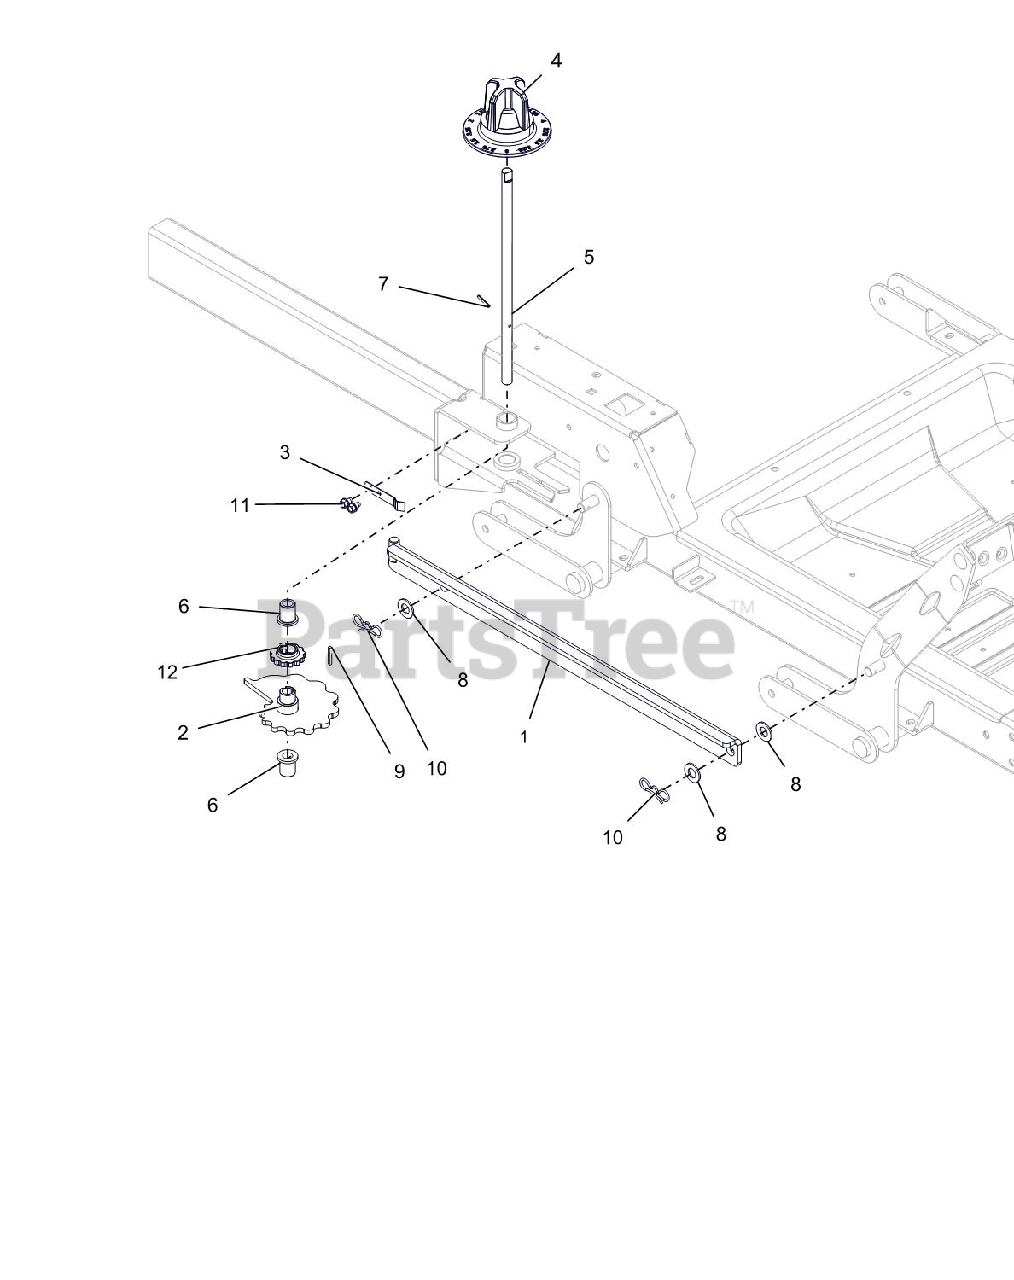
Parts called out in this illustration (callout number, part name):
1	WLDMT, HOC LINK
2	WLDMT, HOC CAM
3	ARM, HOC DETENT
4	KNOB, HOC DIAL
5	SHAFT, HOC CAM IKON
6	BSHG-FLG, .503X.750X.875X1.00
7	PIN-ROLL .125X1.00
8	WSHR-FL-NYL .518X1.000X.080
9	KEY, 1/8 X 1/8 X 1.0
10	PIN,BOW TIE LOCKING .091X1.875
11	@SCR-TAP .25-20X.37 HWH YWZ TR
12	GEAR, HOC INDEX
